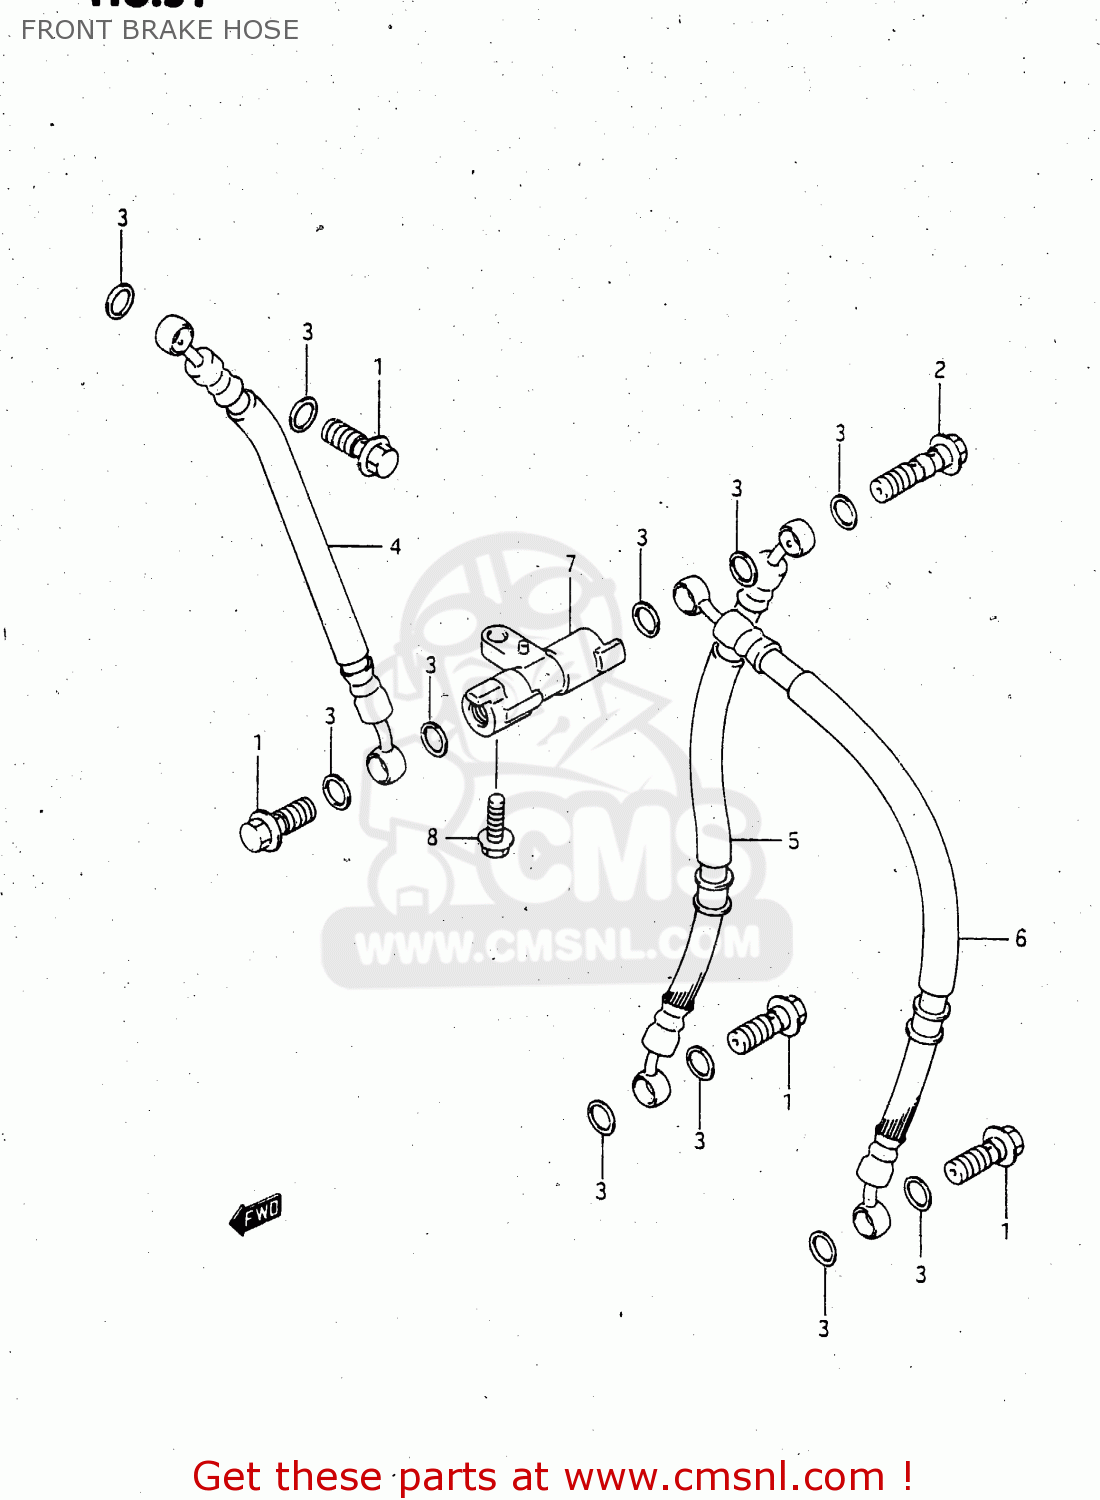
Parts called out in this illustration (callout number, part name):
1	BOLT UNION
2	BOLT UNION
3	WASHER(10X15X1.5)
4	HOSE,FR BRAKE NO.1
5	HOSE,FR BRAKE NO.2,R
6	HOSE,FR BRAKE NO.2,L
7	JOINT,BRAKE HOSE
8	BOLT
